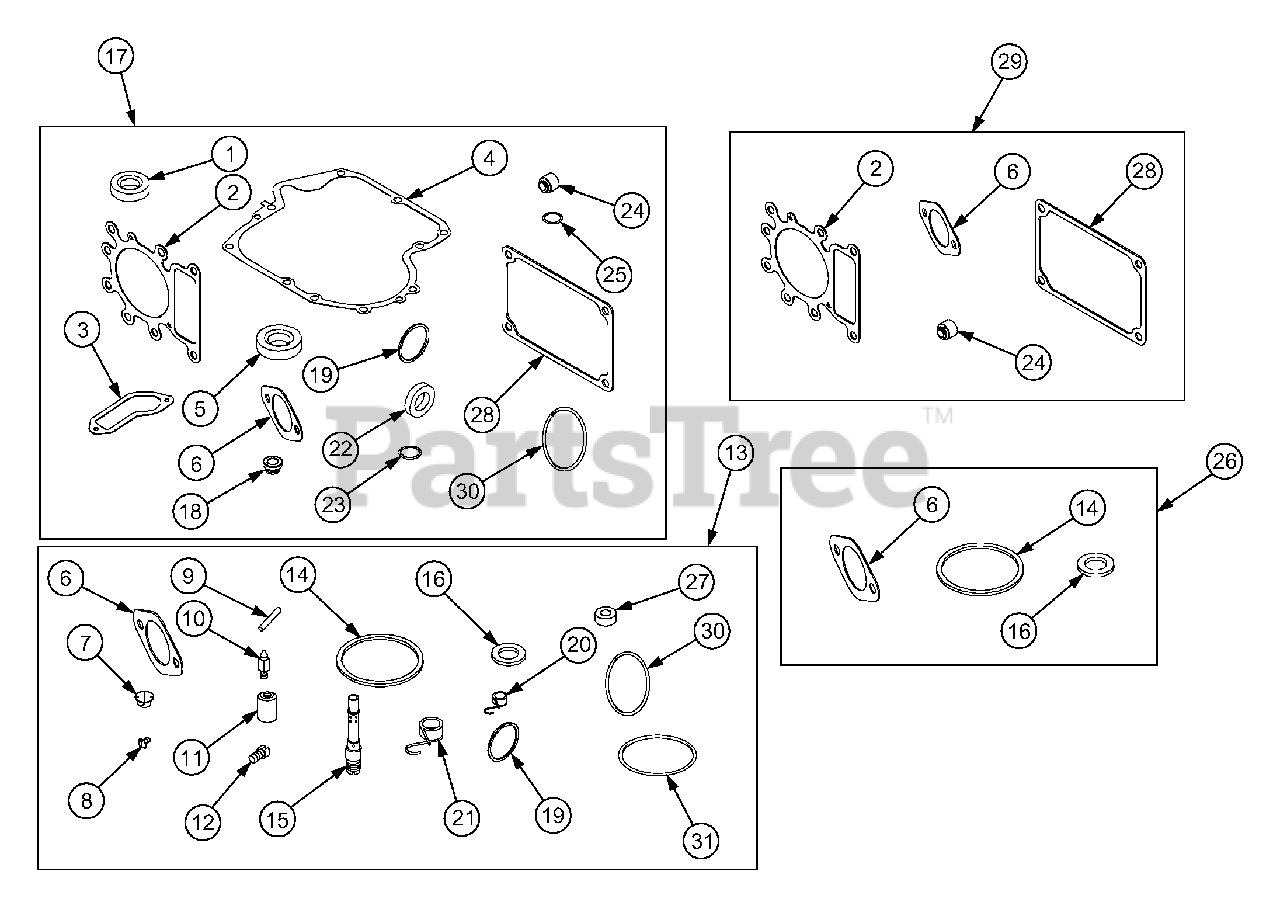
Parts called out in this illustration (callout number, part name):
1	Seal, Oil
2	Gasket, Cylinder Head
3	Gasket, Breather
4	Gasket, Crankcase
5	Seal, Oil
6	Gasket, Intake
7	Bushing, Throttle Shaft
8	Screw, Throttle Valve
9	Pin, Float Hinge
10	Valve, Float Needle
11	Seal, Inlet (LMT 697204)
13	Kit, Carburetor Overhaul
14	Gasket, Float Bowl
15	Nozzle, Carburetor
16	Sealing Washer
17	Gasket Set, Engine
18	Seal, Dipstick Tube
19	O-Ring Seal
20	Spring/Seal Assembly
21	Spring/Seal Assembly
22	Seal, Governor Shaft
23	Seal, O-Ring
24	Seal, Valve
25	O-Ring Seal
26	Set, Carburetor Gasket
27	Seal, Throttle Shaft
28	Gasket, Rocker Cover
29	Gasket Set, Valve
30	O-Ring Seal
31	O-Ring Seal
